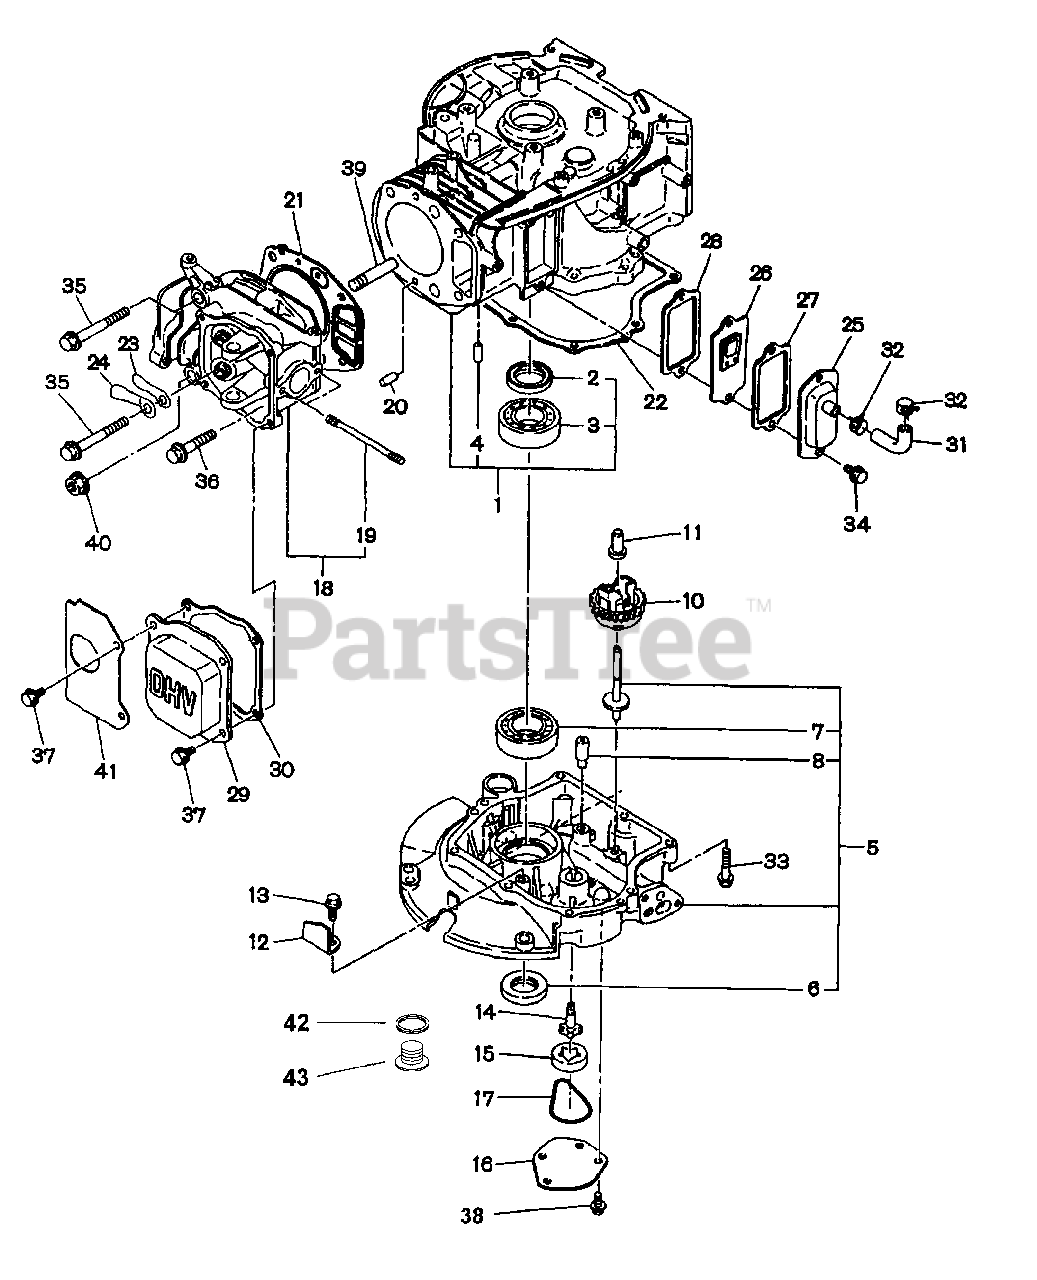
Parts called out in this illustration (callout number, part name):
1	CRANKCASE, compl.
3	BALL BEARING
5	MAINBEARING COVER, compl.
6	OIL SEAL
7	BALL BEARING
10	GOVERNOR GEAR, compl.
11	GOVERNOR SLEEVE
12	OIL SHELTER PLATE
13	FLANGE BOLT
14	OIL PUMP, inner., compl.
15	OIL PUMP, outer
16	OIL PUMP COVER
17	O-RING
18	CYLINDER HEAD, compl.
21	GASKET, head
22	GASKET, bearing cover
24	RETAINER PLATE
25	TAPPET COVER, compl.
26	BREATHER PLATE, compl.
27	GASKET, tappet cover
28	GASKET, breather plate
29	ROCKER COVER, yellow zinc (Pro Poly)
29	ROCKER COVER, silver zinc (Classic Steel)
30	GASKET, Rocker Cover
31	RUBBER PIPE (8ø X 11mm)
33	BOLT and WASHER ASS'Y
34	FLANGE BOLT
35	FLANGE BOLT
36	FLANGE BOLT
37	FLANGE BOLT
38	FLANGE BOLT
40	NUT, Flange
41	GUIDE PLATE
42	O-RING, OIL DRAIN PLUG
43	OIL DRAIN PLUG
